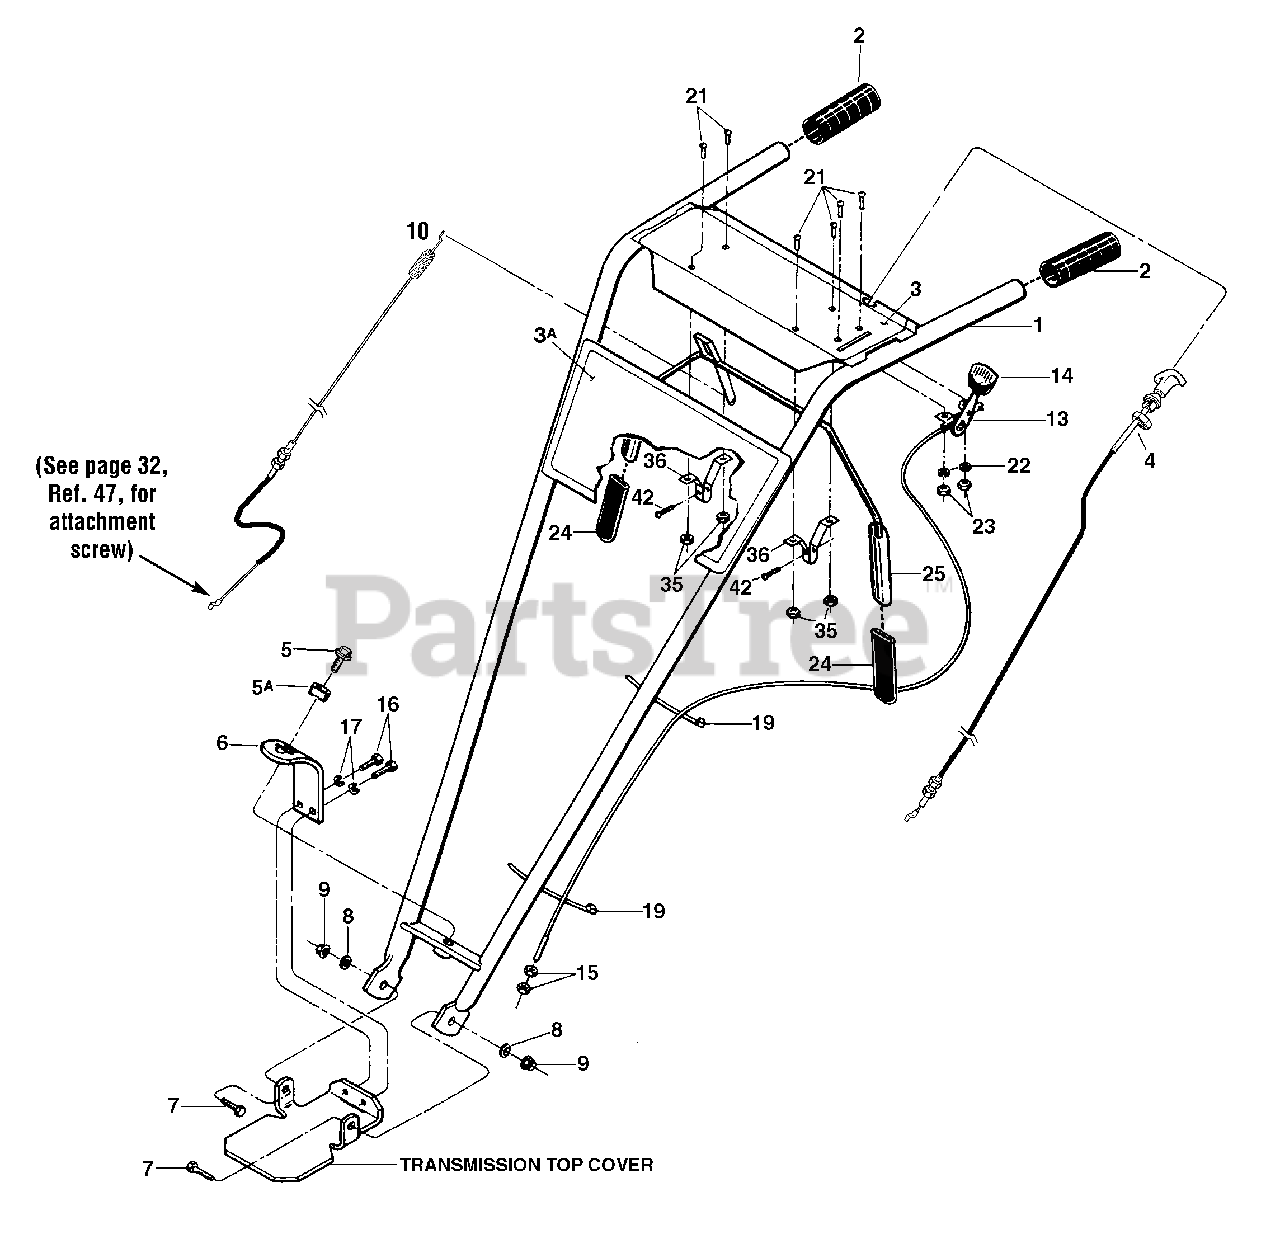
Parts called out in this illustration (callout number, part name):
1	Handlebars
2	Grip
3	Decal, Control Panel
3A	Decal, Model Name/Logo
4	Reverse Clutch Control Cable
5	Height Adjustment Screw
5A	Washer, Keyed
6	Bracket, Handlebar Height Adjustment
7	Hex Hd. Screw, 3/8-16 x 1
8	Washer, Plain (flat) 3/8, S.A.E.
9	Hex Locknut, 3/8-16
10	Cable, Forward Clutch Control
13	Wheel Gear Control and Cable Assy.
14	Knob, Wheel Gear Control Lever
15	Hex Nut, 5/16-24
16	Hex Hd. Screw, 3/8-16 x 3/4
17	Lockwasher, 3/8
19	Cable Ties, Plastic
21	Round Hd. Screw, #10-32 x 1/2
22	Lockwasher, #10
23	Hex Nut, #10-32
25	Bail, Forward Clutch Control
36	Bracket, Bail Support
42	Hex Flange Screw, self-tapping, 1/4-20 x 1/
